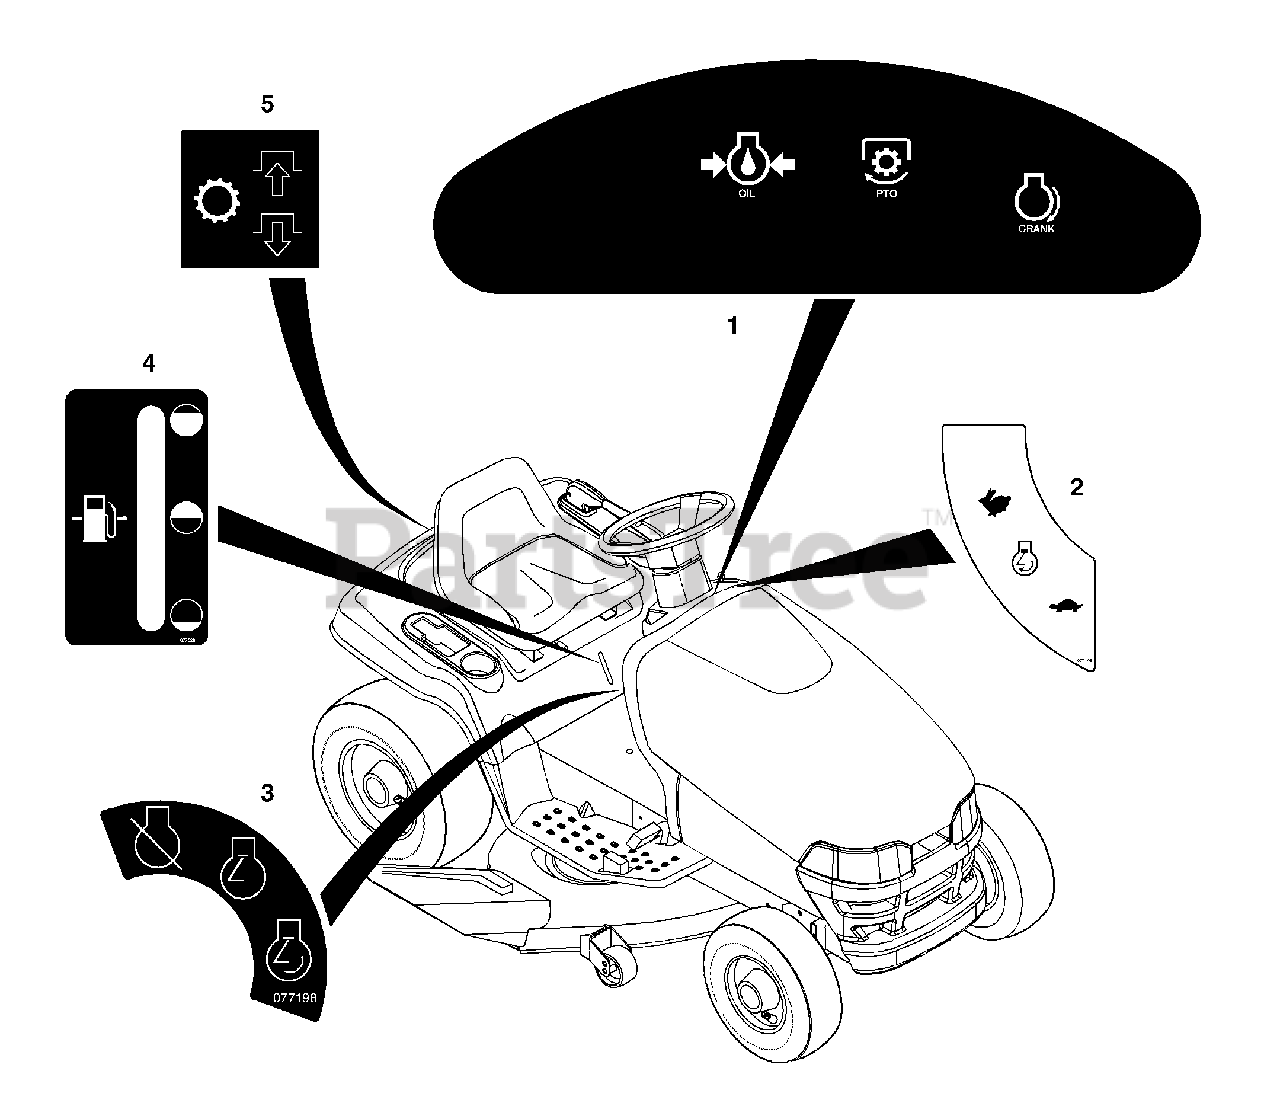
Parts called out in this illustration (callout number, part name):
1	DECAL - DASH W/LIGHTS
2	DECAL- THROTTLE W/O CHOKE
3	DECAL - IGNITION
4	DECAL- FUEL LEVEL
5	DECAL-TRANS. DISCONNECT
